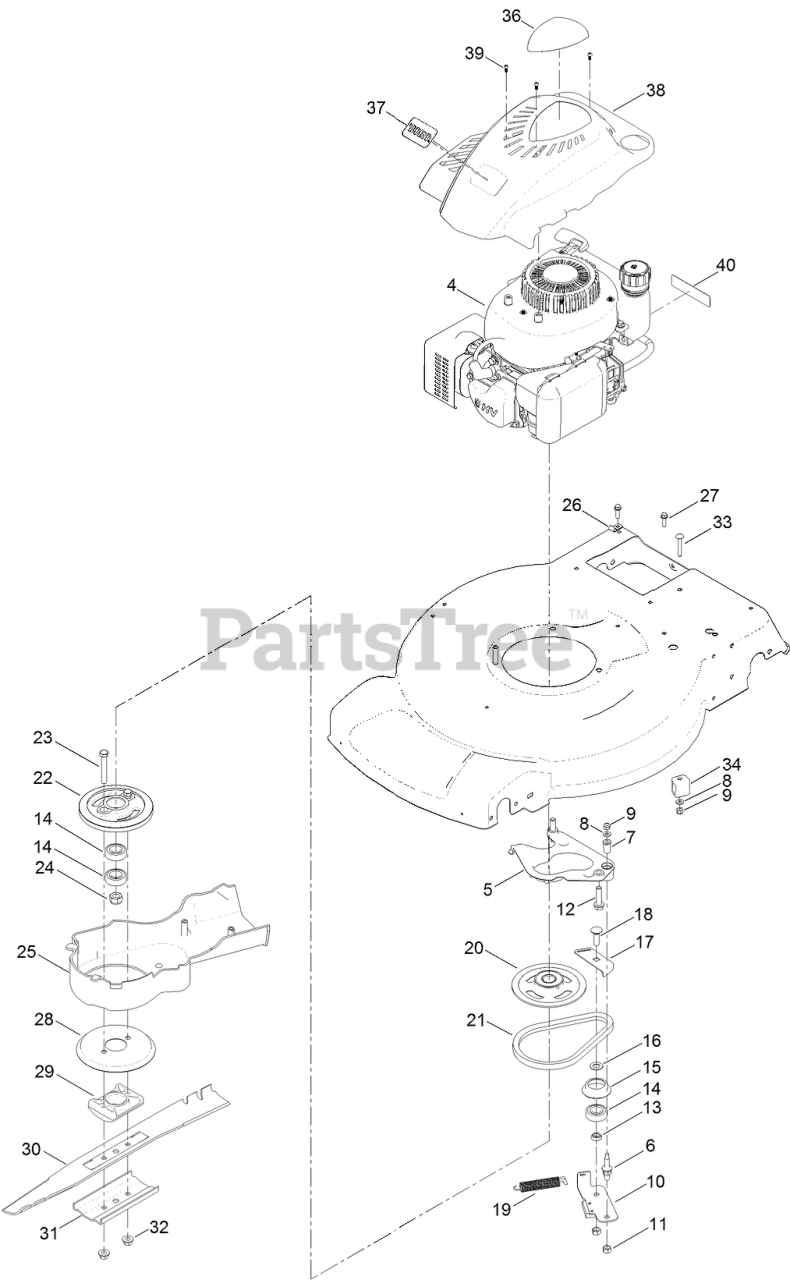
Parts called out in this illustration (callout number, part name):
4	ENGINE-1P65FC
5	PLATE-ANCHOR
6	BOLT-SHOULDER
7	BUSHING
8	WASHER-FLAT
9	NUT-LOCK, NI
10	PLATE-BRAKE
11	NUT-HEX
12	SCREW-HWH
13	SPACER-BEARING
14	BEARING-BALL
15	RETAINER-BELT
16	WASHER-PLAIN
17	PLATE-GUIDE
18	BOLT-CARR
19	SPRING-TENSION, BRAKE
20	PULLEY
21	BELT
22	DRUM
23	SCREW-HH
24	NUT-HEX
26	CLIP-CLOSED, INSULATED
27	SCREW-HWH
28	DISC
29	SUPPORT-BLADE
30	BLADE-22 INCH
31	SUPPORT-BLADE
32	NUT-FLANGE, LOCK
33	SCREW-CARR
34	ANCHOR-CABLE
36	DECAL-SHROUD
38	SHROUD
39	SCREW-PPH
40	DECAL-ARRESTER, SPARK
